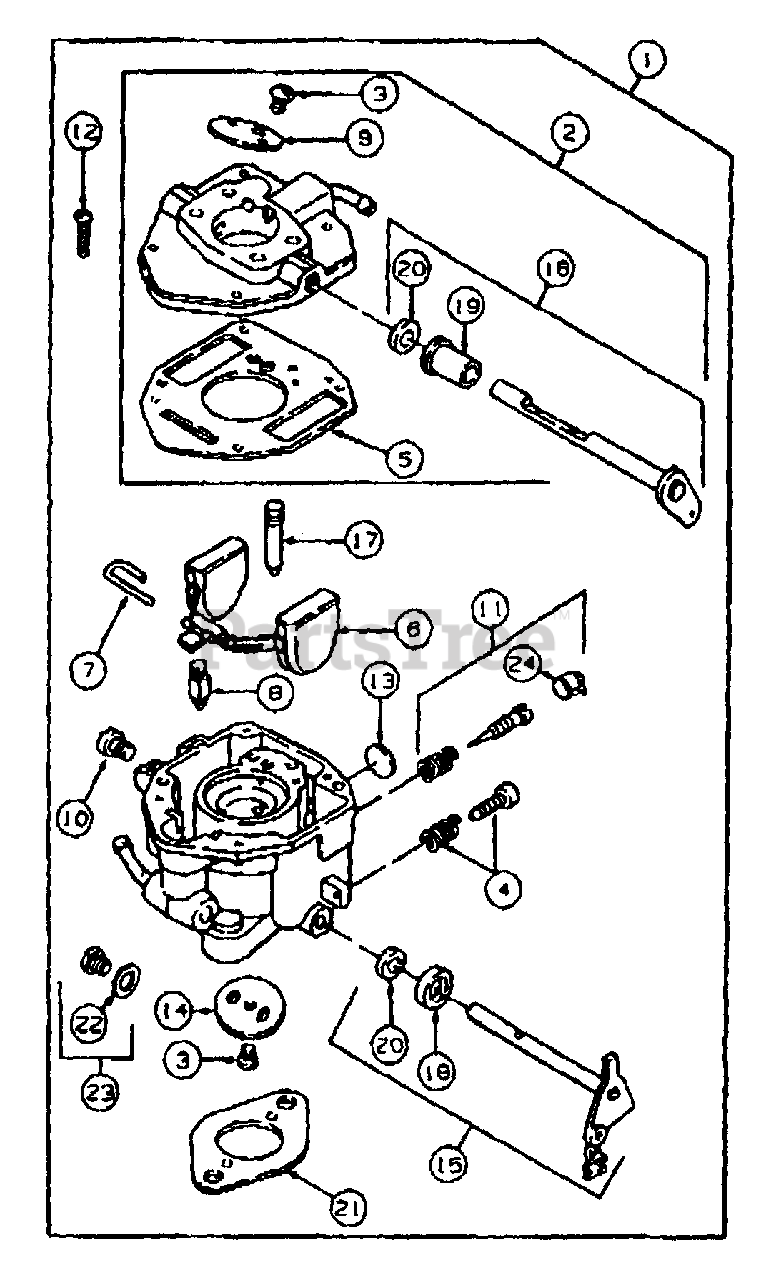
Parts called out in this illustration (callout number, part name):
1	Carburetor Assembly
2	Body, Upper Carb.
3	Screw, Valve Mounting
4	Screw, Throttle Adjustment
5	Gasket, Intake Elbow
6	Float Assembly
7	Pin, Float Hinge
8	Valve, Fuel Inlet
9	Valve, Choke
10	Jet, Main
11	Valve, Idle Adjusting Needle
12	Screw, Upper Body Mounting
13	Plug, Welch
14	Valve Throttle
15	Shaft, Throttle
16	Shaft, Choke
17	Jet, Slow Speed
18	Collar, Throttle
19	Collar, Choke
20	Seal, Shaft
21	Gasket, Carburetor Mounting
22	O-Ring
24	Cap, Limiter
